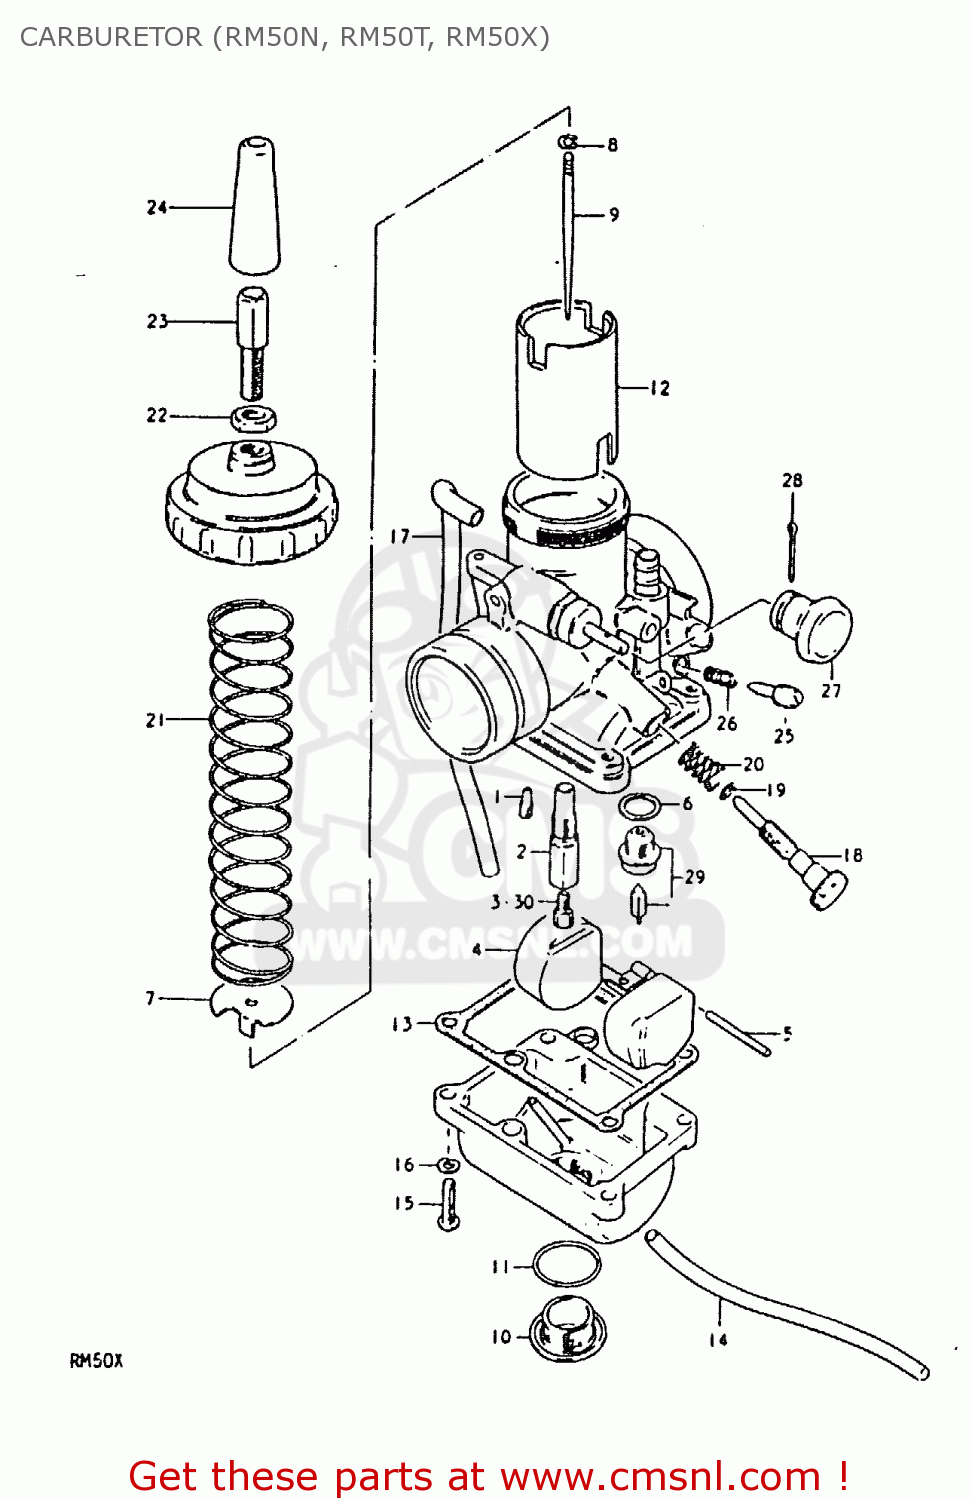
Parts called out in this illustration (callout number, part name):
1	JET,PILOT (17.5)
2	JET,NEEDLE
3	JET, MAIN
4	FLOAT
5	PIN,FLOAT
6	GASKET,NEEDLE VALVE (NAS)
7	STOPPER,NEEDLE CLIP
8	CLIP
9	NEEDLE JET
10	SCREW,GUIDE
11	O-RING
12	VALVE,THROTTLE
13	GASKET, FLOAT CHAMBER
14	HOSE
15	SCREW
16	LOCK WASHER
17	HOSE
18	ADJUSTER
19	O-RING
20	SPRING
21	SPRING,THROTTLE VALVE
22	NUT
23	ADJUSTER
24	CAP,CABLE ADJUSTER
25	SCREW,PILOT AIR
26	SPRING
27	LEVER
28	COTTER PIN
29	VALVE ASSY,NEEDLE
30	JET
